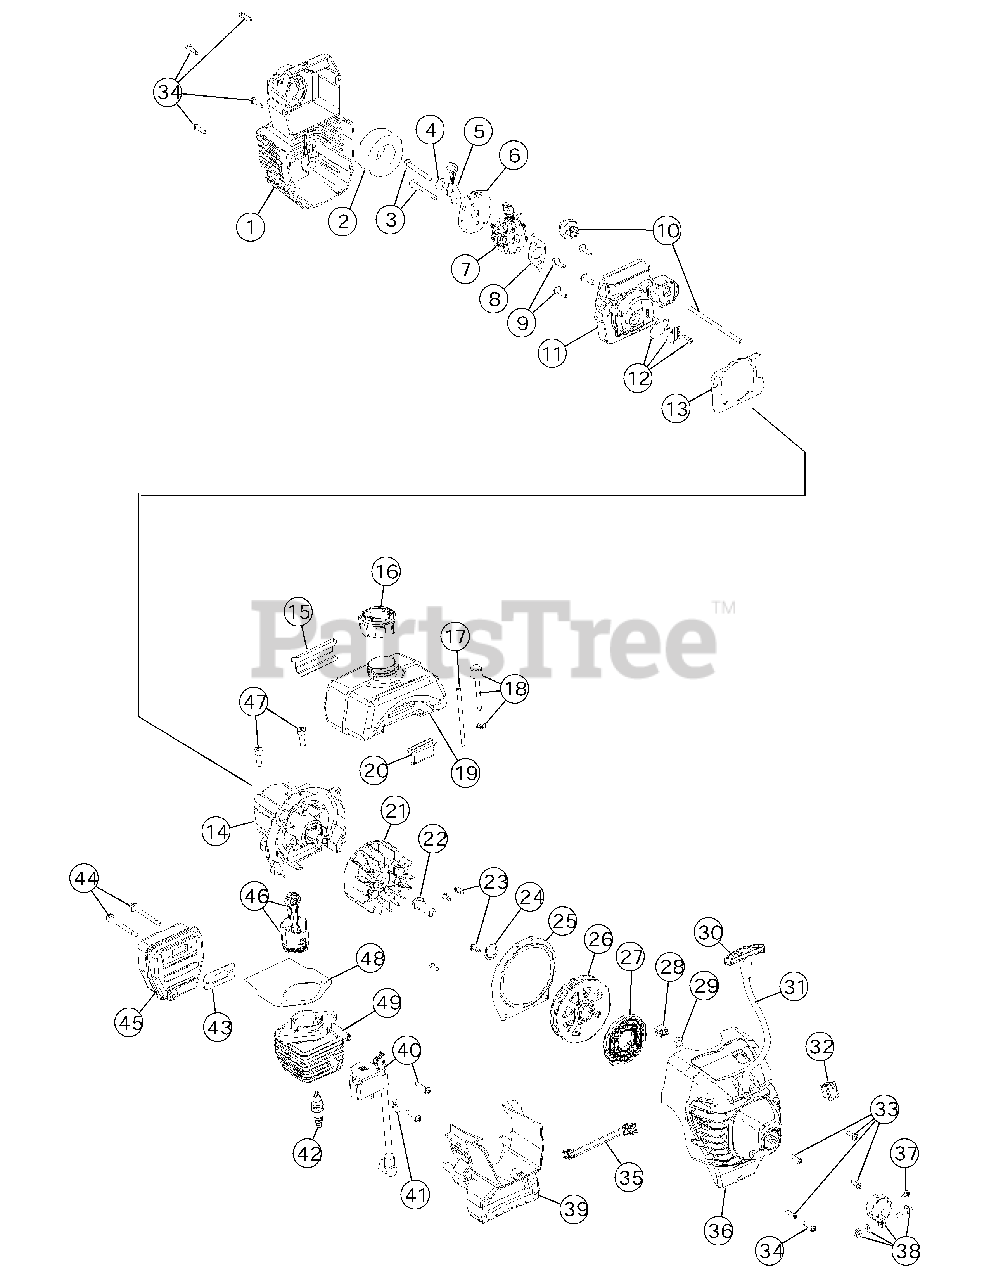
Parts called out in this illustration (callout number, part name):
1	Air Cleaner Cover Assembly (includes 2 & 34)
2	Air Cleaner Filter
3	Carburetor Mounting Screws
4	Wavey Washer
5	Choke Lever Assembly
6	Choke Lever & Plate (includes 5)
7	Carburetor Assembly (includes 8 & 19)
8	Carburetor Gasket
9	Carb Mount Screw
10	Primer and Hose Assembly
11	Carburetor Mount Assembly (includes 9, 12 & 13)
12	Reed Assembly
13	Carburetor Mount Gasket
14	Crankcase Service Assembly (includes 9)
15	Rear Mounting Pad
16	Fuel Cap Assembly
17	Fuel Return Line
18	Fuel Line Assembly
19	Fuel Tank Assembly (includes 16-18)
20	Front Mounting Pad
21	Flywheel Assembly
22	Square Nut Drive
23	Plate Screw
24	Palnut
25	Pressure Plate (includes 23 & 28)
26	Recoil Pulley Assembly (includes 24)
27	Recoil Spring
28	Eyelet Retainer
29	Rope Guide
30	Pull Handle
32	Switch Assembly
33	Housing Screw
34	Cover Screw
35	Wire Lead
36	Starter Housing Assembly (includes 23-35)
37	Anti-Rotation Screw
38	Clamp Assembly (includes 37)
39	Shroud Extension and Stand (includes 34)
40	Module Assembly
41	Ground Tab
42	Spark Plug
43	Exhaust Gasket
44	Muffler Mounting Bolt Assembly
45	Muffler Assembly (includes 43 & 44)
46	Piston & Rod Assembly
47	Cylinder Bolt
48	Cylinder Gasket
49	Cylinder Assembly (includes 47 & 48)
